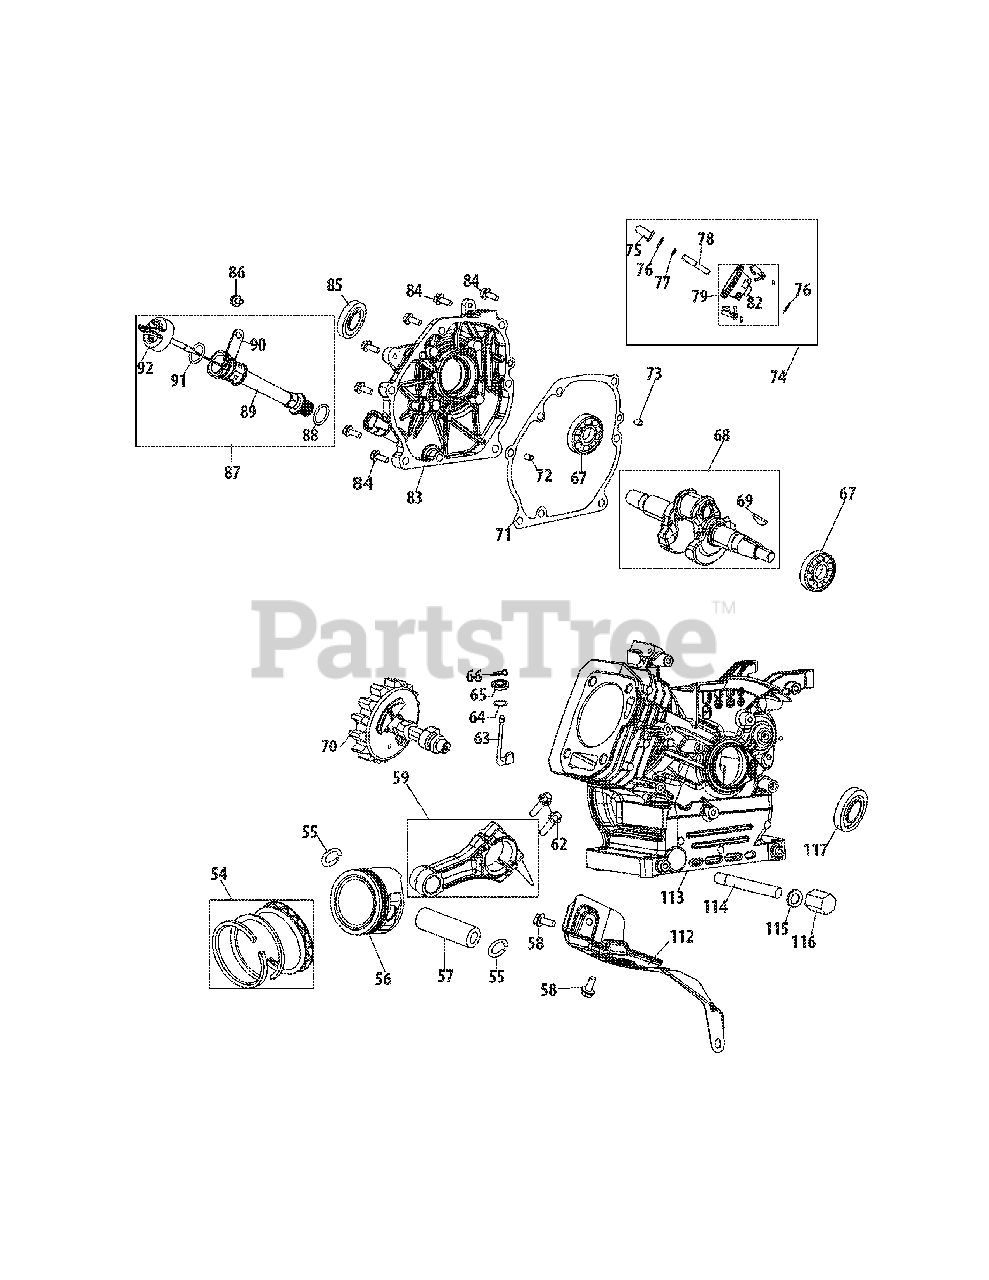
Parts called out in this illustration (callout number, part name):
54	PISTON RING SET
55	CIRCLIP
56	PISTON
57	WRIST PIN
58	BOLT M6×12
59	CONNECTING ROD
62	CONNECTING ROD BOLT
63	SHAFT,GOVERNOR ARM
64	O-RING 5.2×1.9
65	OIL SEAL 6×11×4
66	COTTER PIN
67	BEARING 6205
68	CRANKSHAFT
69	WOODRUFF KEY
70	CAMSHAFT
71	GASKET, CRANKCASE COVER
72	DOWEL PIN 9×14
73	DOWEL PIN 7×14
74	GOVERNOR GEAR
75	GOVERNOR CUP
76	WASHER 6.2×0.6×15
77	RETAINING RINGS, GOVERNOR SHAFT
78	GOVERNOR SHAFT
79	GOVERNOR B0DY
82	GOVERNOR GEAR
83	CRANKCASE COVER
84	BOLT M8×32
85	OIL SEAL 25×41.25×6
86	BOLT M6×16
87	DIPSTICK
88	O-RING 15.5×1.5
89	DIPSTICK SEAT
90	EMBRACEHOOP
91	O-RING 21×2.77
92	DIPSTICK
112	SHROUD
113	CRANKCASE
114	OIL DRAIN PIPE
115	WASHER 10×1.5×16
116	WASHER,DRAIN BOLT(M10×1.25×15)
117	OIL SEAL 25×41.25×6
